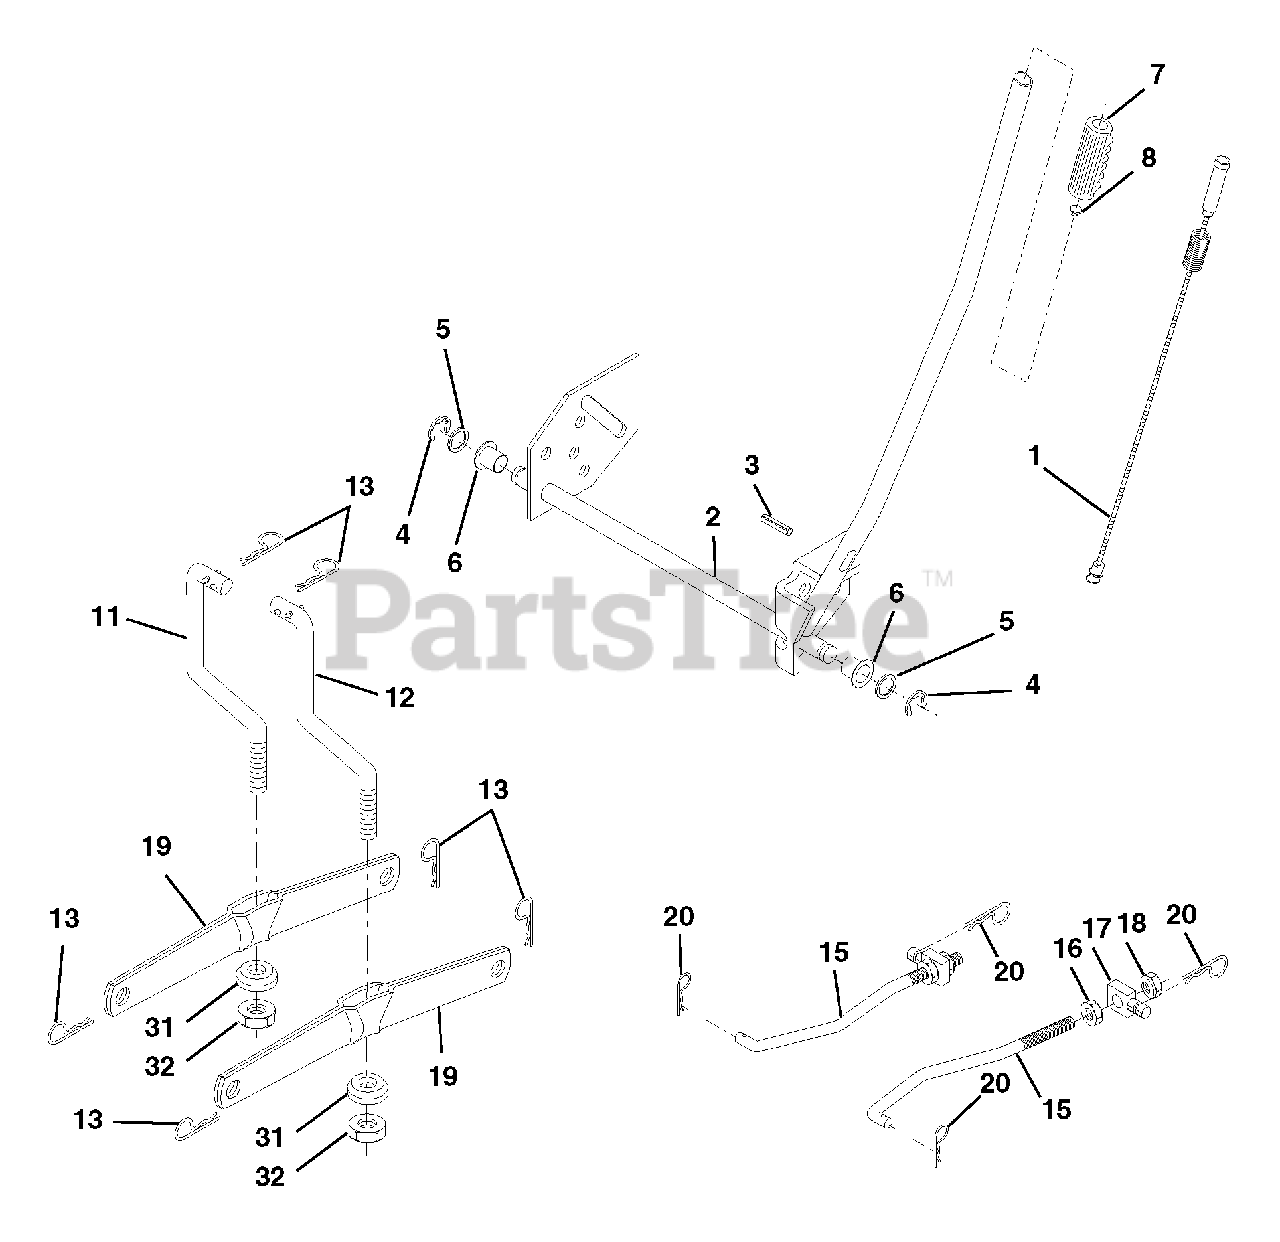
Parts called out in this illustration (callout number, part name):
1	Wire Asm Inner W/plunger LT
2	Shaft Asm Lift
3	Pin Groove
4	E Ring #5133-62
5	Washer PLTD 21/32 x 1 x 21Ga.
6	Bearing Nylon Blk 629 Id
7	Grip Handle Bicycle
8	Button Plunger Black
11	Link Lift LH
12	Link Lift RH
13	Retainer Spring
15	Link Front
16	Nut Jam Hex 1/2-13 unc
18	Nut Lock W/Wsh 1/2-13 unc
19	Arm Suspension Rear
20	Spring, Retainer
31	Bearing Pvt. Lift
32	Nut Crownlock 3/8-24
